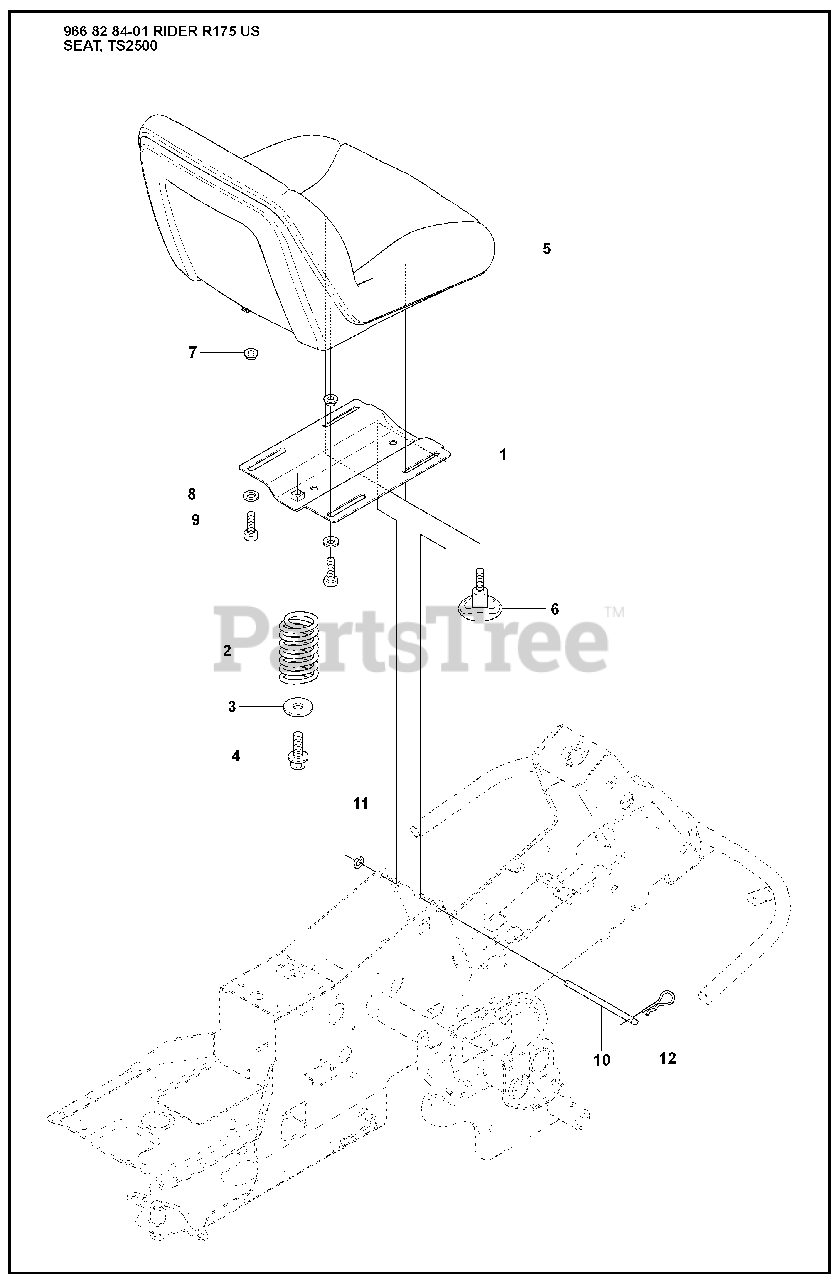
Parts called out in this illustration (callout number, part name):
1	SEAT BRACKET
2	SEAT SPRING
4	Screw, M10 X 25
5	SEAT
6	ADJUSTING KNOB
11	RETAINING RING SGA 10
